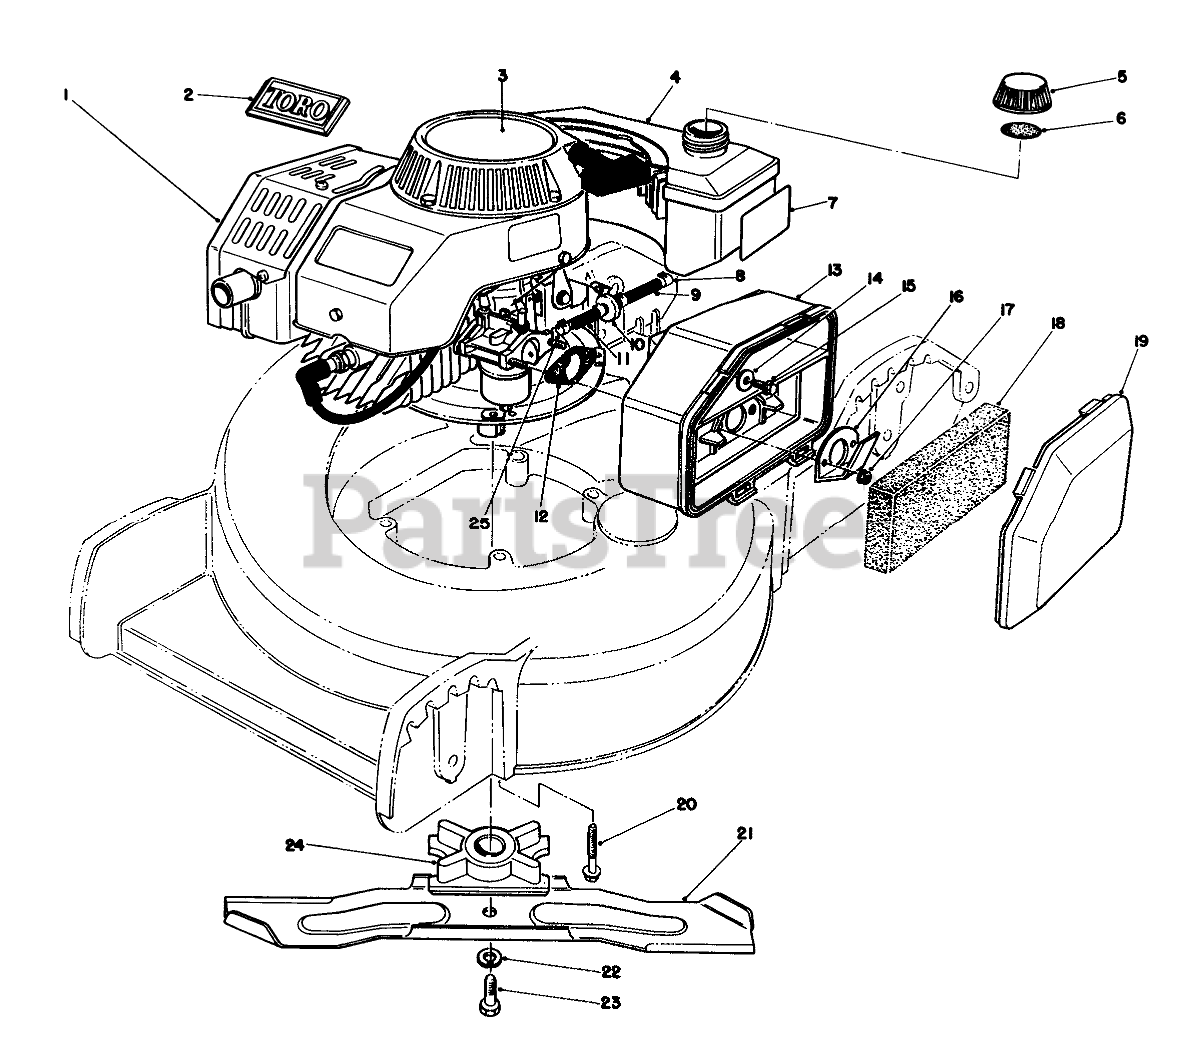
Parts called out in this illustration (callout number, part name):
1	Engine
2	TORO LOGO PLT
3	DECAL- 2 CYC RECOIL
4	Gas Tank Assembly
5	Gas Cap Assembly (Incl. Ref. #6)
6	GAS CAP GASKET
7	Decal-Maintenance
8	CLAMP-FUEL LINE
9	HOSE-FUEL
10	FILTER-FUEL
11	HOSE-FUEL
12	GASKET-AIR CLEANER
13	AIR CLEANER
14	WASHER-FLAT
15	SCREW-HH
16	SPIT BACK DEFLECTOR
17	NUT-LOCK
18	FILTER
19	AIR CLEANER COVER
20	SCREW-HHF
21	Blade
22	WASHER-LOCK
23	SCREW-HH
24	BLADE RETAINER
25	CLAMP-HOSE
